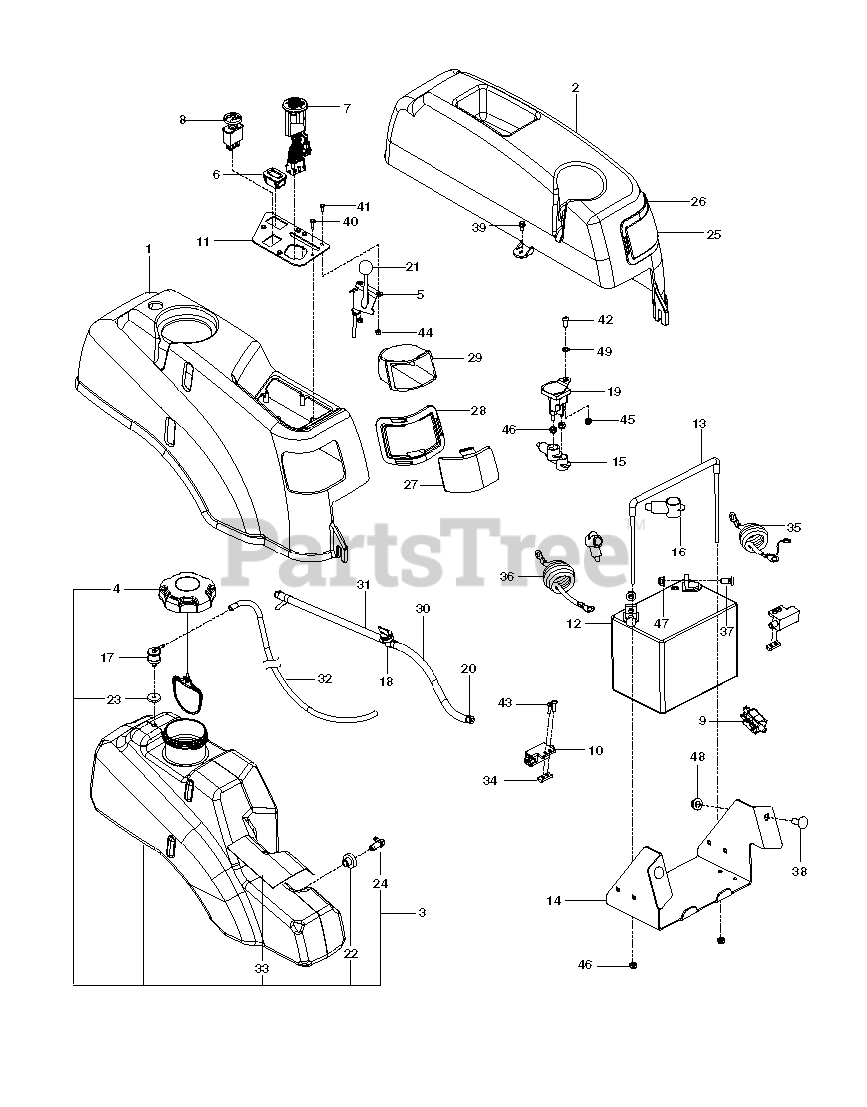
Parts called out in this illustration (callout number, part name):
1	FENDER RT, GRAY
2	FENDER, LT
3	TANK.FUEL.ASSEMBLY.LARGE
4	CAP, FUEL
5	THROTTLE CONTROL W/BALL KNOB
6	RP.GUAGE.SRVCMNDR.HRMTR.
7	2013 RZ SMART SWITCH
8	RP SWITCH.PTO.8.TERMINAL.RED
9	SWITCH, BRAKE 3P
10	SWITCH INTERLOCKT
12	BATTERY, 12 V 330 AMP
13	BATTERY TIE DOWN ASSEMBLY
14	BOX, BATTERY, BLACK
15	TERMINAL COVER-SM
17	VALVE.FUEL.CHECK
18	FUEL VALVE
19	SOLENOID.W/BRASS.PLUNGER
20	HOSE CLAMP
21	KNOB.ROUND.BALL.BLACK
22	RUBBER GROMMET
23	GROMMET, CHECK VALVE
24	STEM, FUEL TANK
25	LENS, COLORED LEFT
26	LEFT HEADLIGHT RIM GREY
27	LENS, COLORED RIGHT
28	RT HEADLIGHT RIM GREY
29	REFLECTOR, LEFT HEAD LIGHT
29	REFLECTOR, HEADLIGHT RT
30	GAS LINE 10"
31	FUEL LINE 3"
32	HOSE, VAPOR 3/16 X 15"
33	SHIELD, HEAT
34	TAPPED PLATE
35	CABLE POSITIVE, LONG
36	BATTERY CABLE, NEGATIVE
37	BOLT 5/16C X 3/4" CARRIAGE
38	RHSNB 3/8C X 1
39	BOLT 1/4-20 X 1/2 HWST
40	SCR #10-12X3/4 HEX WAS HD ZD
41	HCS #10-24 X 1/2
42	SCR 1/4-20 X 5/8 BTN SKT HD ZD
43	SCR #10-24 X .75 SKT HD BLK
44	NUT 10-24 NYLOC
45	HCS M5-0.8 X 16MM GR 8.8 ZD
46	NUT.1/4-20.HEX.NYLOC.ZD
47	5/16-18 NYLOC FLANGE NUT
48	NUT 3/8-16 HEX FLG NYLOC ZD
49	WASHER 1/4 INT TOOTH
